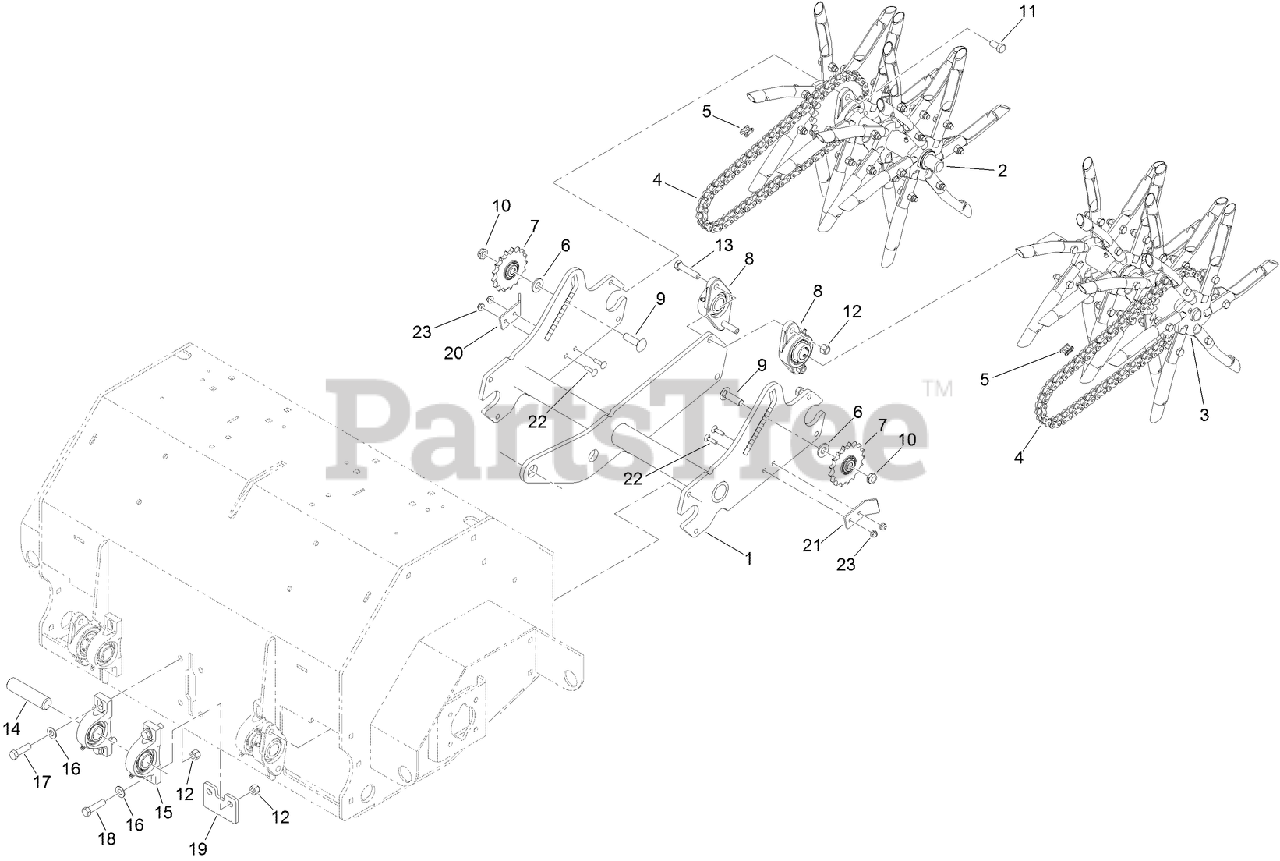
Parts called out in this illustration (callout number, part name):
1	ARM-TRAIL
2	RH TINE WHEEL ASM
3	LH TINE WHEEL ASM
4	CHAIN-ROLLER, #50, 65 LINKS
5	LINK-CONNECTING
6	WASHER-THRUST
7	SPROCKET-IDLER, 17T
8	BEARING-FLANGE, 2 BOLT
9	SCREW-CARR
10	NUT-LOCK, NI
11	SCREW-HH
12	NUT-LOCK, NI
13	SCREW-HH
15	BEARING-PILLOW BLOCK
16	WASHER-FLAT
17	SCREW-HH
18	SCREW-HH
19	PLATE-DOWNSTOP
20	GUARD-CHAIN, RH
21	GUARD-CHAIN, LH
22	SCREW-CARR
23	NUT-HF
